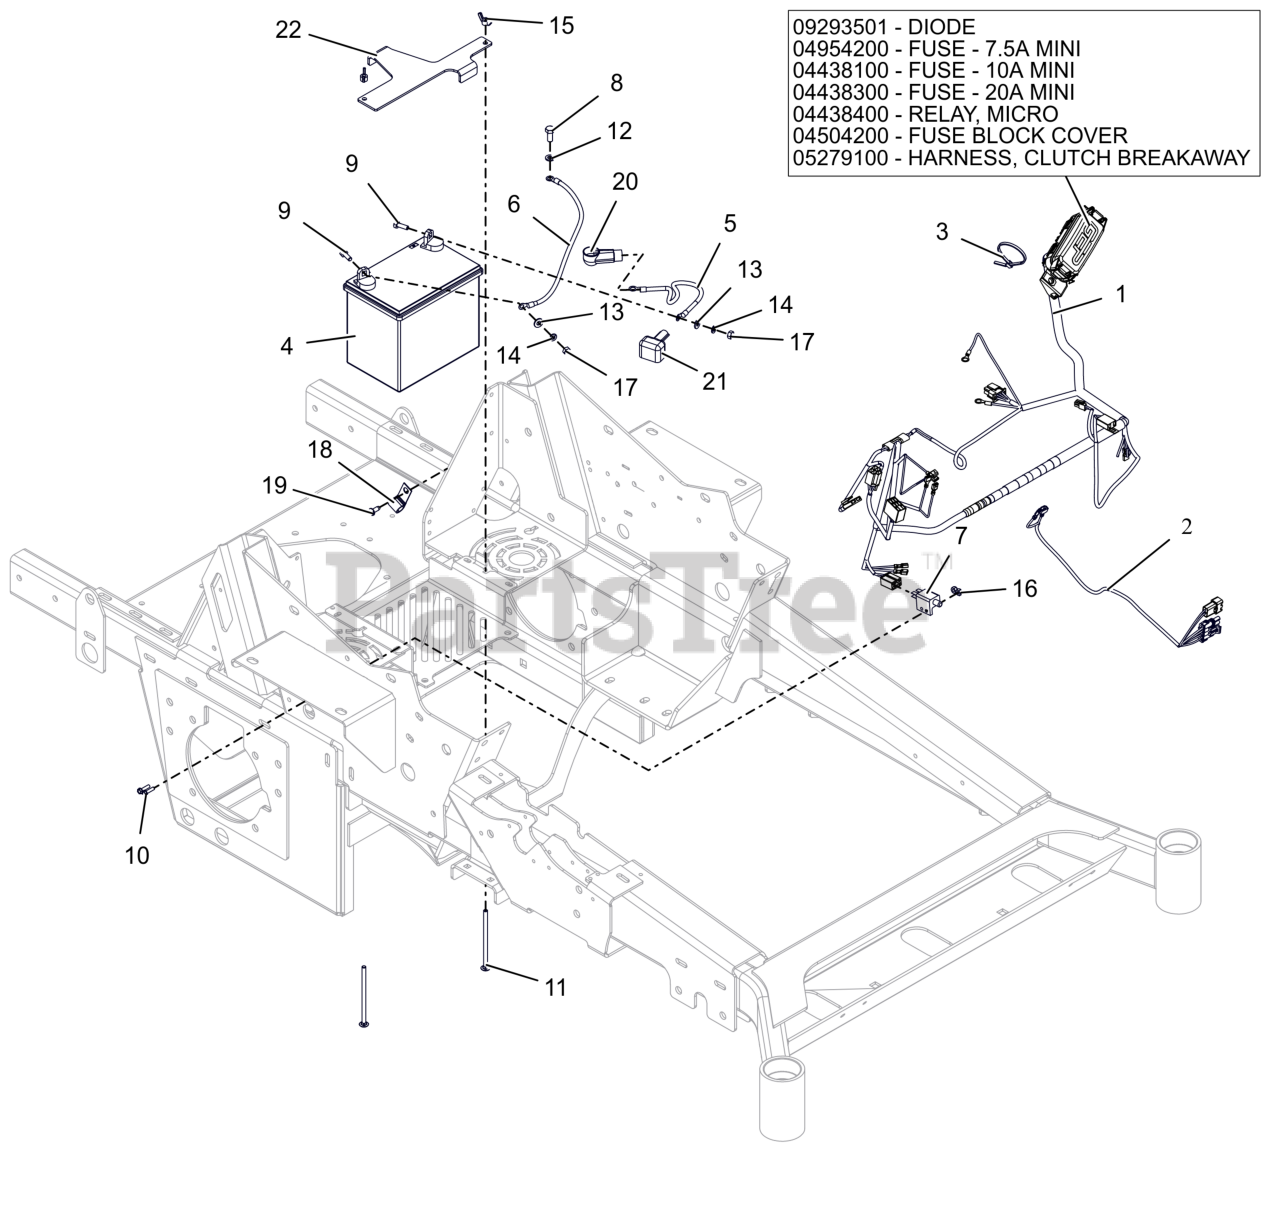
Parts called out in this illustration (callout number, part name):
1	HARNESS- WIRE PT300 MAIN
1	DIODE, CONNECTOR SHELL
1	FUSE, 7.5 AMP MINI-ATC
1	FUSE,10 AMP MINI-ATC
1	FUSE,20 AMP MINI ATC
1	RELAY,MICRO5 TERML W/RESISTOR
1	COVER, HARNESS FUSE/RELAY MOD
1	HARNESS, CLUTCH BREAKAWAY
2	HARNESS- AIR RIDE SEAT
3	CABLE TIE, .15 X 8.50
4	BATTERY, 300 CCA 10U1L
5	CABLE, STARTER 13.00"
6	CABLE-GROUND .25 X 13.00 X .31
7	SWITCH- DOUBLE POLE N.O./N.O.
8	BLT, HEX M8-1.25X20 G8.8 ZCC
9	BLT, HEX .25-20X.75 G5 ZCC
10	BLT, HWH #10-24X.75 ZCC
11	BLT, RHSN .25-20X4.50 G5 ZCC
12	WSHR,LK-REG .312X.078 ZCC
13	WSHR,FLT .281X.625X.065 ZCC
14	WSHR,LK-REG .250X.062 ZCC
15	NUT, LK-WING .25-20 ZCC
16	NUT-LK-NYL #10-24 G2 ZCC
17	NUT-STD .250-20 G2 ZCC
19	SCR,TAP .25-20X.625 HWH ZCC
20	BOOT, .65ID POS
21	INSULATOR
22	HOLDDOWN- BATTERY
